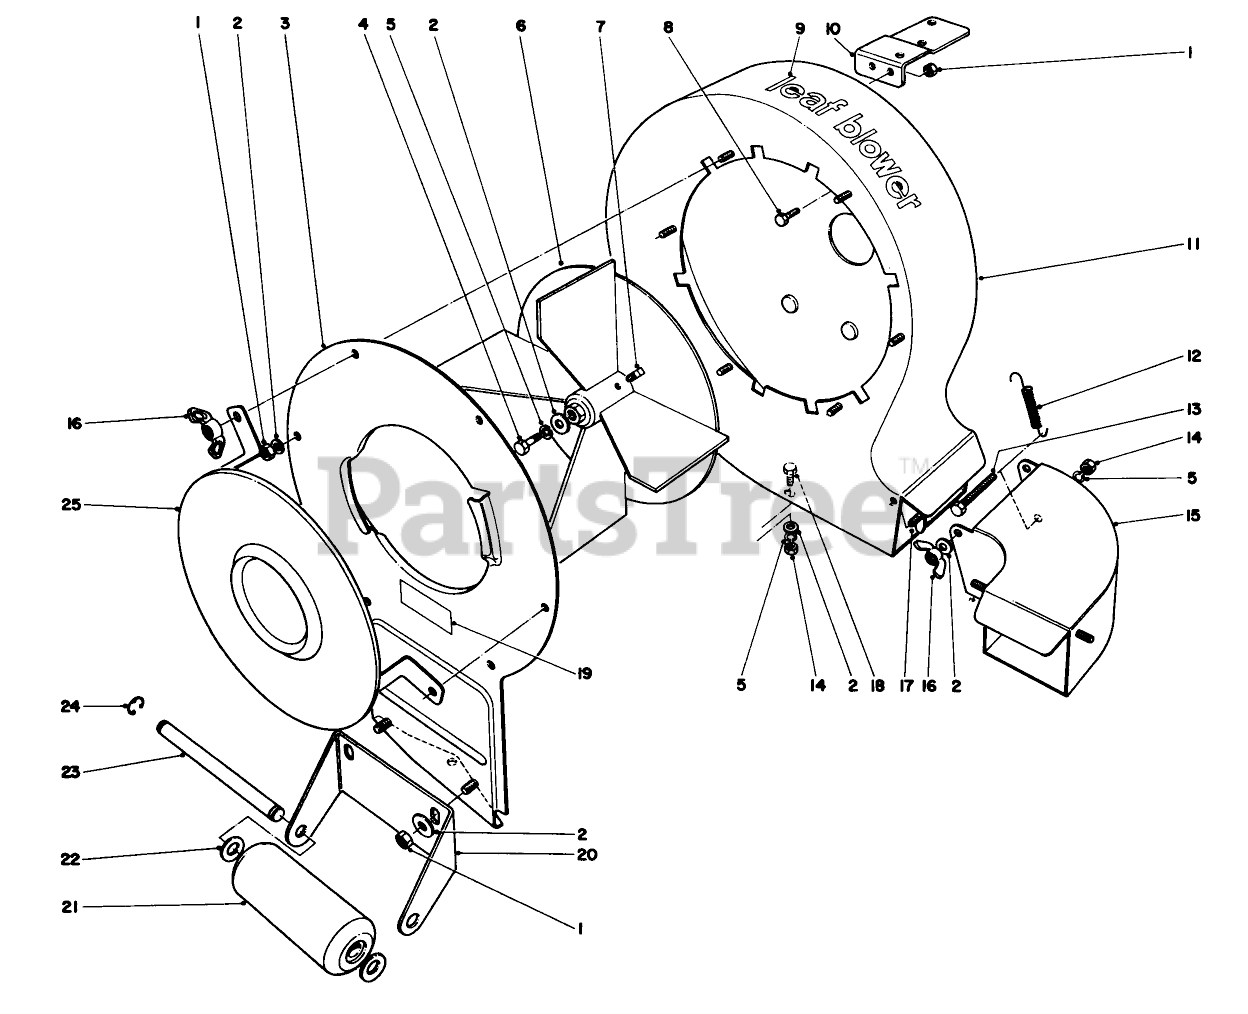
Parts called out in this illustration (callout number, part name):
1	Nut
2	WASHER-FLAT
3	Front Plate
4	Special Bolt
5	WASHER-LOCK/SP
7	SCREW-SQH
8	SCREW-HH
9	Decal, Leaf Blower
10	Blower Housing Bracket
11	Blower Housing
12	Deflector Spring
13	Special Bolt
14	NUT-HEX
15	Deflector
16	NUT-WING
17	Special Bolt
18	SCREW-HH
19	Caution Decal
20	Roller Bracket
21	Roller
22	Special Washer
23	Roller Axle
24	Retaining Ring
25	Guard
